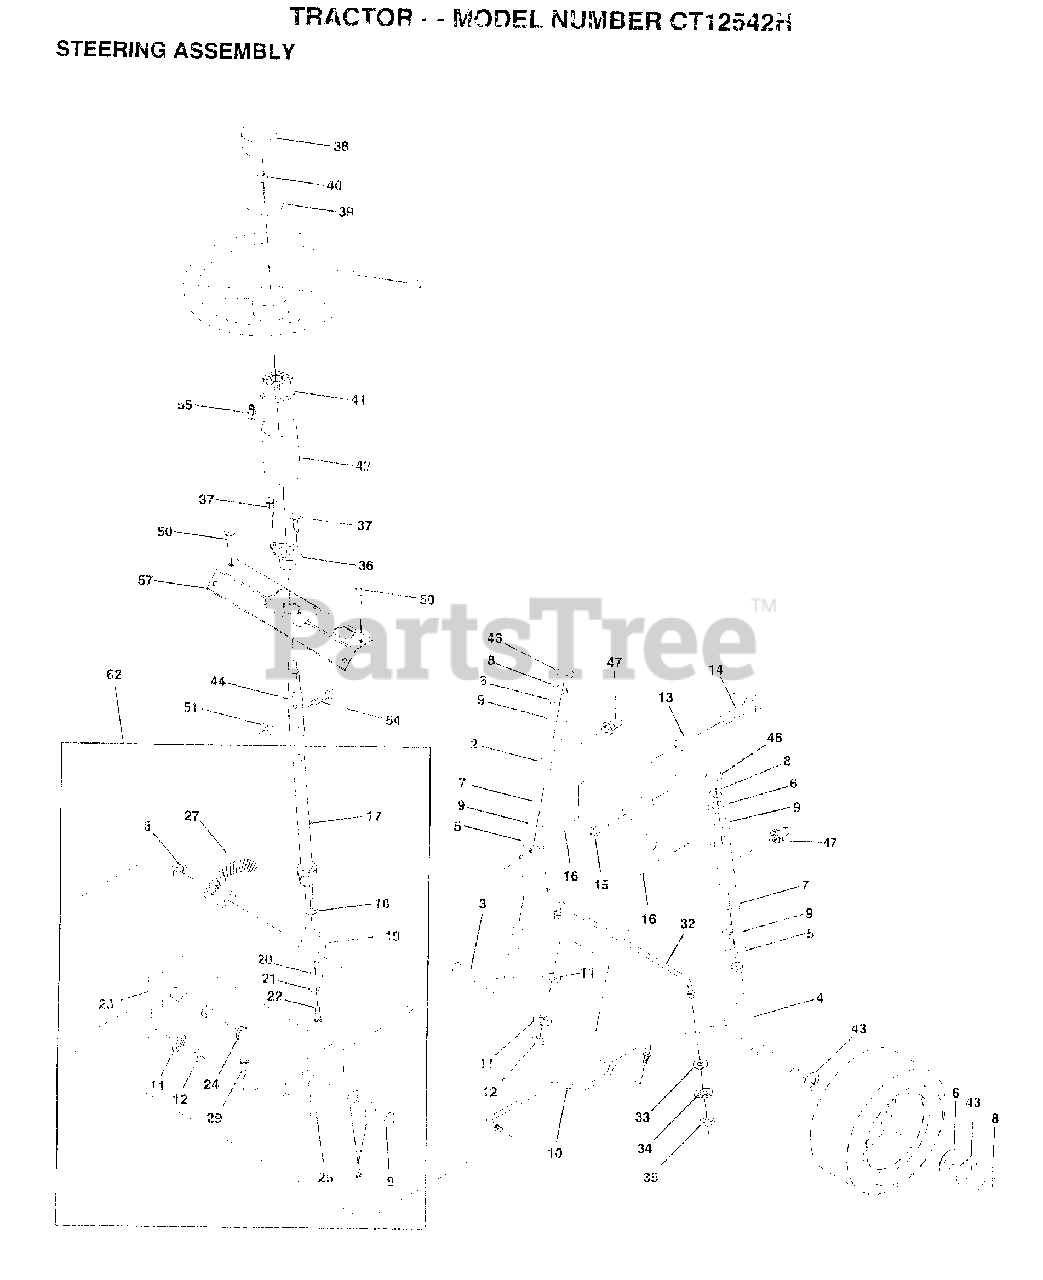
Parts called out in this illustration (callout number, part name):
1	WHEEL STR AYP BLK
2	AXLE ASM FRONT
3	SPINDLE LH
4	SPINDLE RH
5	WASHER .T
6	WASHER
7	WASHER
8	RING
9	COL. SRTG. BEAR.
11	LOCKWASHER
13	BEARING
14	BOLT HEX 5/8-11
15	"NUT-LOC,FLANGE LT"
16	AXLE PIN
17	SHAFT ASM STEERIN
18	THRUST WASHER
19	SUPPORT.SHAFT
21	LOCKWASHER
22	SCREW.SCKTHD.CAP
24	NYLINER T
25	"BRKT,STEERING"
27	GEAR SECTOR
29	SCREW
32	ROD.TIE.19.75
33	WASHER M
34	LOCKWASHER
35	NUT.LOCK.5/16-24
38	CAP STEER AYP
39	WASHER T
40	GRIPCO NUT
41	ADAPTER-WHEEL LT
42	BOOT SHAFT STEER
43	WASHER
46	CAP
47	ZERK M
50	SCREW HEX CRT
51	NUT
54	BOLT
55	CLIP TINNERMAN
57	SUPPORT SHAFT STR
